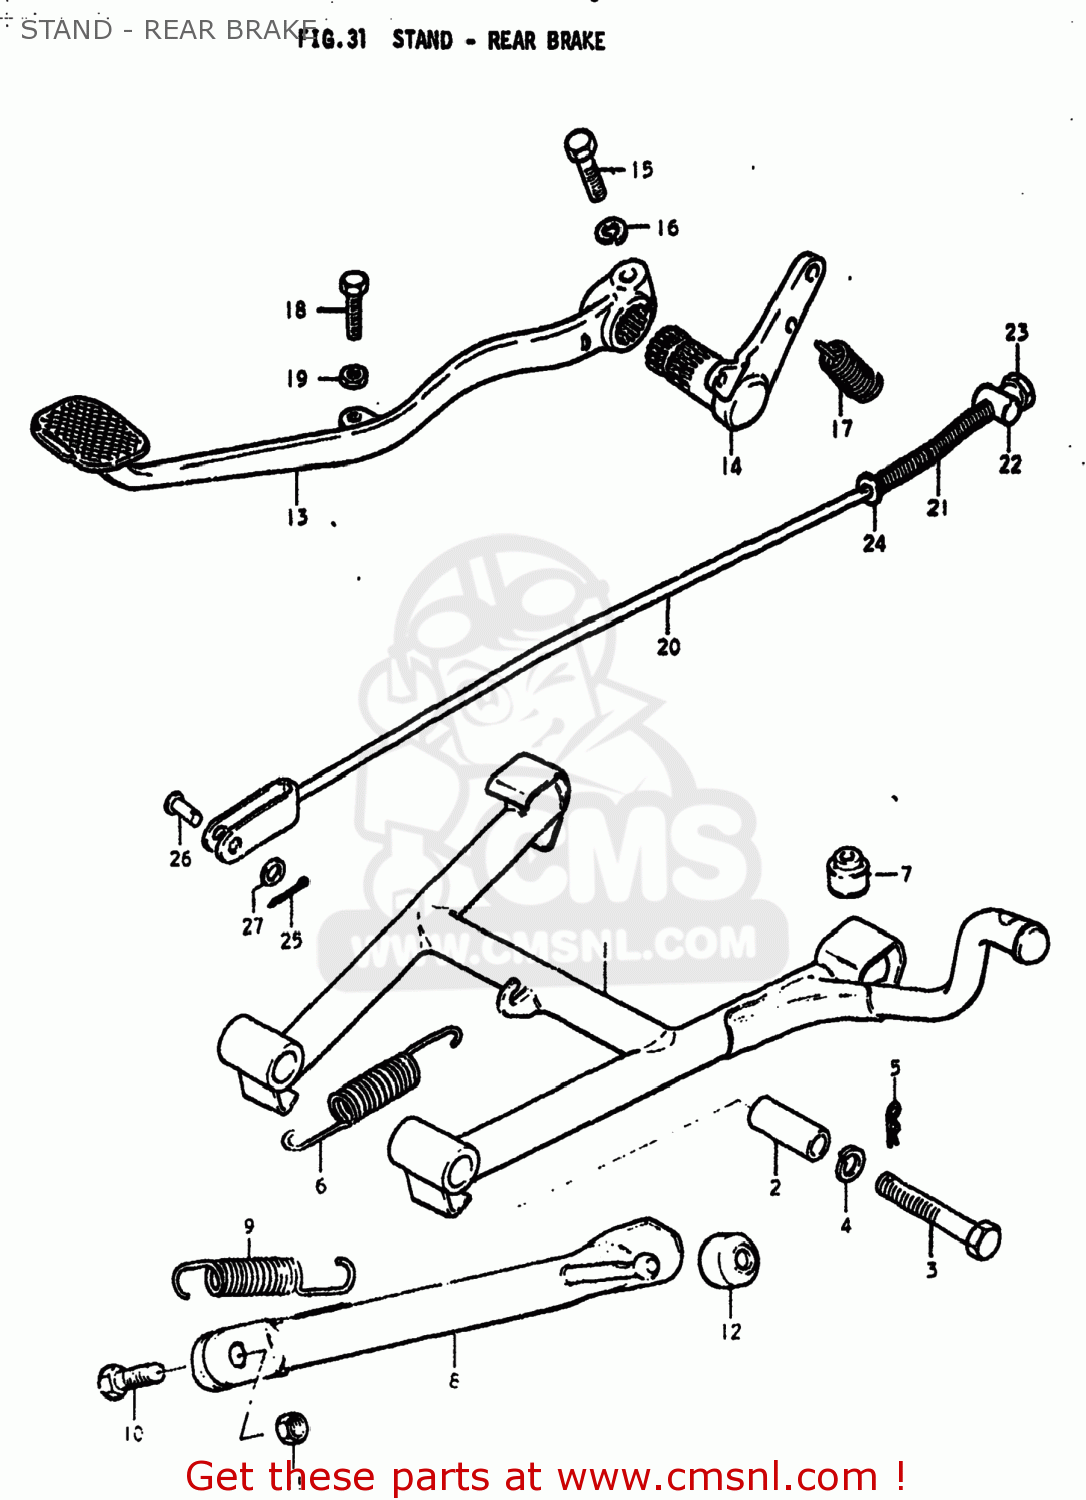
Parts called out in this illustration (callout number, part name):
1	STAND,CENTER
2	SPACER(10X16X38.8)
3	BOLT
4	LOCK WASHER
5	CLIP
6	SPRING
7	CUSHION
8	STAND,SIDE
9	SPRING
10	BOLT(10X30)
11	NUT
12	CUSHION
13	PEDAL,BRAKE
14	ARM,BRAKE PEDAL ROD
15	BOLT
16	LOCK WASHER
17	SPRING
18	BOLT
19	NUT
20	ROD ASSEMBLY,REAR BRAKE
21	SPRING
22	PIN
23	NUT
24	WASHER
25	PIN 20X20
26	PIN(L:13.5)
27	WASHER
